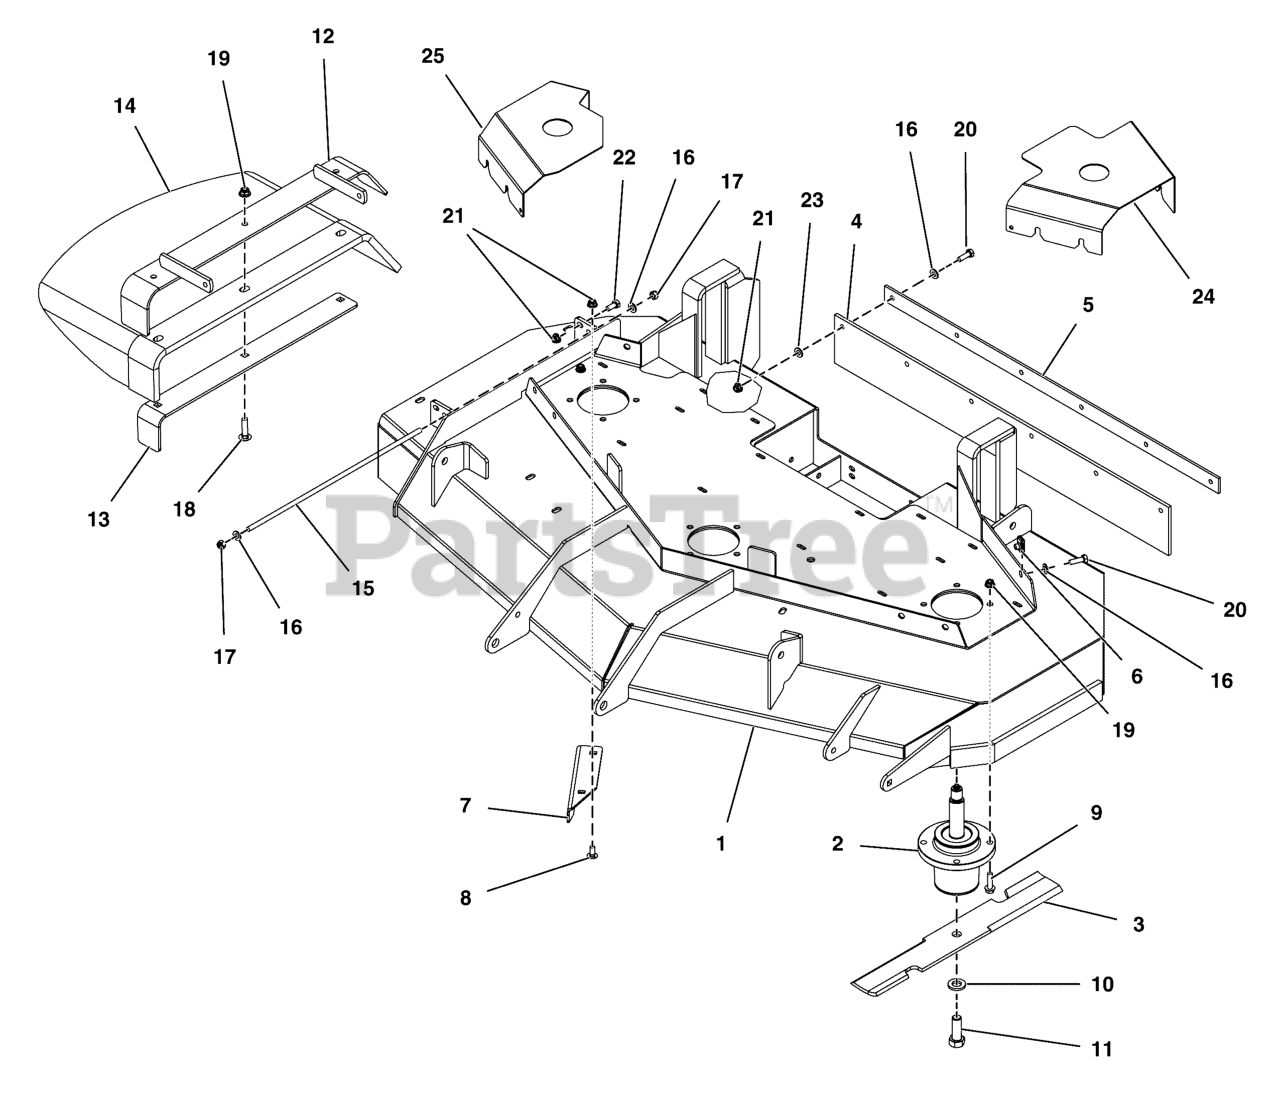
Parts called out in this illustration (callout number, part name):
1	DECK SHELL W/ DECALS, 52, SRSZ2-DOM
1	DECK SHELL W/ DECALS, 52, SRSZ2, (5422061B)
2	SPINDLE ASSM, ALUMINUM, LONG SHAFT
3	BLADE, 18 X .25 X 2.5, 1 X 3.5 (SET OF THREE)
4	FLAP, STRIPER, 61" DECK, IS3100, S200X
5	PLATE, SUPPORT - BLKV
6	BODY CLIP, 5/16-18-7GA MATERIAL
7	PLATE, DEFLECTOR, 52 DECK - BLK
8	BOLT, 5/16-18 X 3/4, CARRIAGE, GD5, CZ
9	BOLT, 3/8-16 X 1-1/2, FLANGE, GD 5, CZ
10	WASHER, BLADE BOLT, 9/16" F436, CZ
11	BOLT, 5/8-11 X 1-3/4 GD8
12	WELD, MOUNT, DISCHARGE CHUTE - BLK
13	SUPPORT, DISCHARGE CHUTE - BLK
14	CHUTE, RUBBER DISCHARGE (5104442)
15	ROD, MOUNT, CHUTE, 61, CZ
16	WASHER, 5/16" SAE
17	NUT, 5/16-24 HEX NYLON LOCK
18	BOLT, 3/8-16 X 1-1/2, CARRIAGE, GD5, CZ
19	NUT, 3/8 - 16 HEX NYLOCK FLANGE
20	BOLT, 5/16-18 X 1" GRD5 YZ
21	NUT, 5/16-18 HEX NYLOCK FLANGE NUT
22	BOLT, 5/16-18 X 3/4 GD5
23	5/16" PUSH-ON NUT RETAINER, STL, CZ
24	GUARD, DECK, 52 - LH - RED
25	GUARD, DECK, 52 - RH - RED
